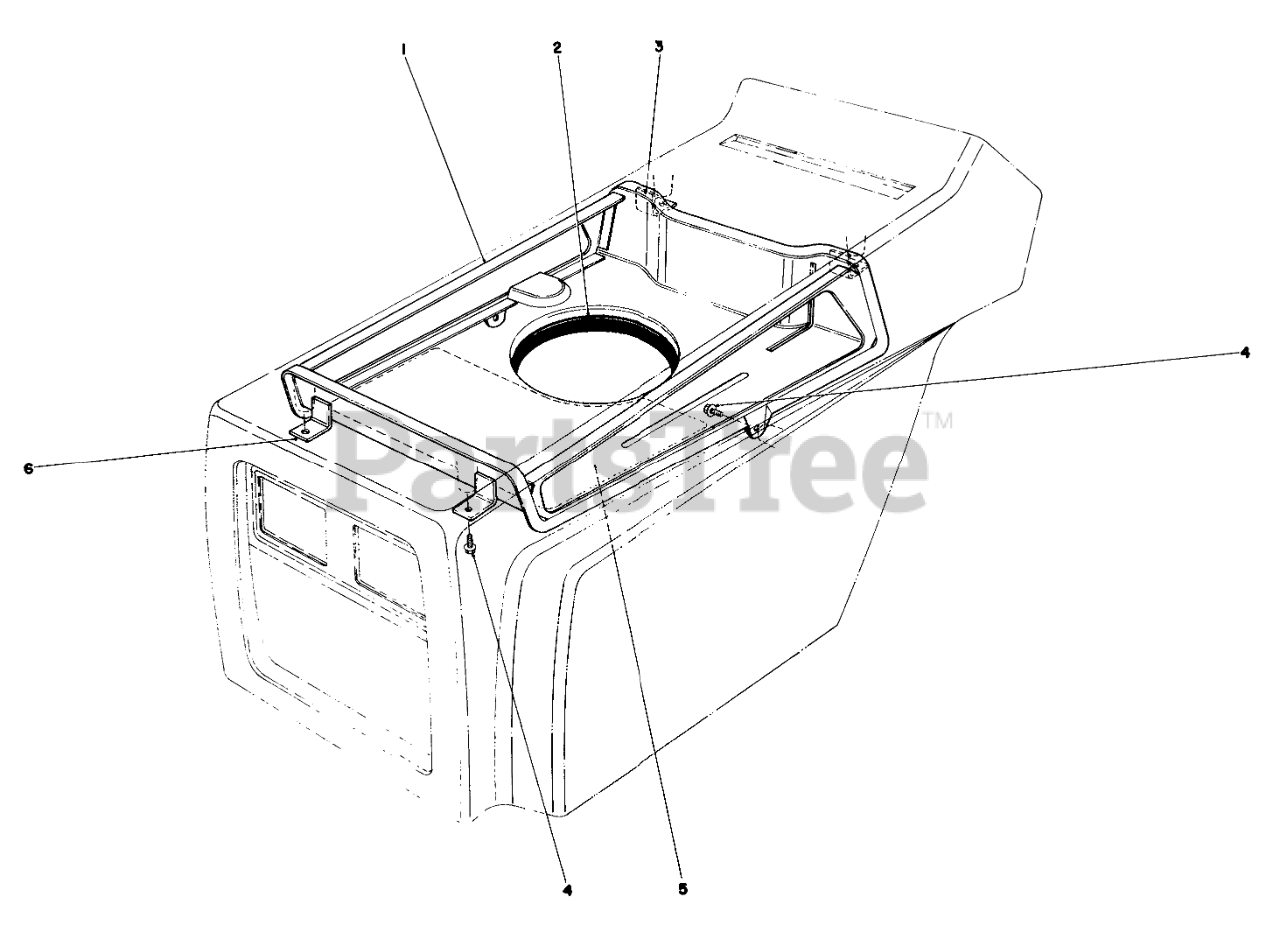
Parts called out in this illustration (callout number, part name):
1	Duct Hood
2	Seal Engine
4	SCREW-HWHTF
5	Decal Service
6	Bracket Duct Support
